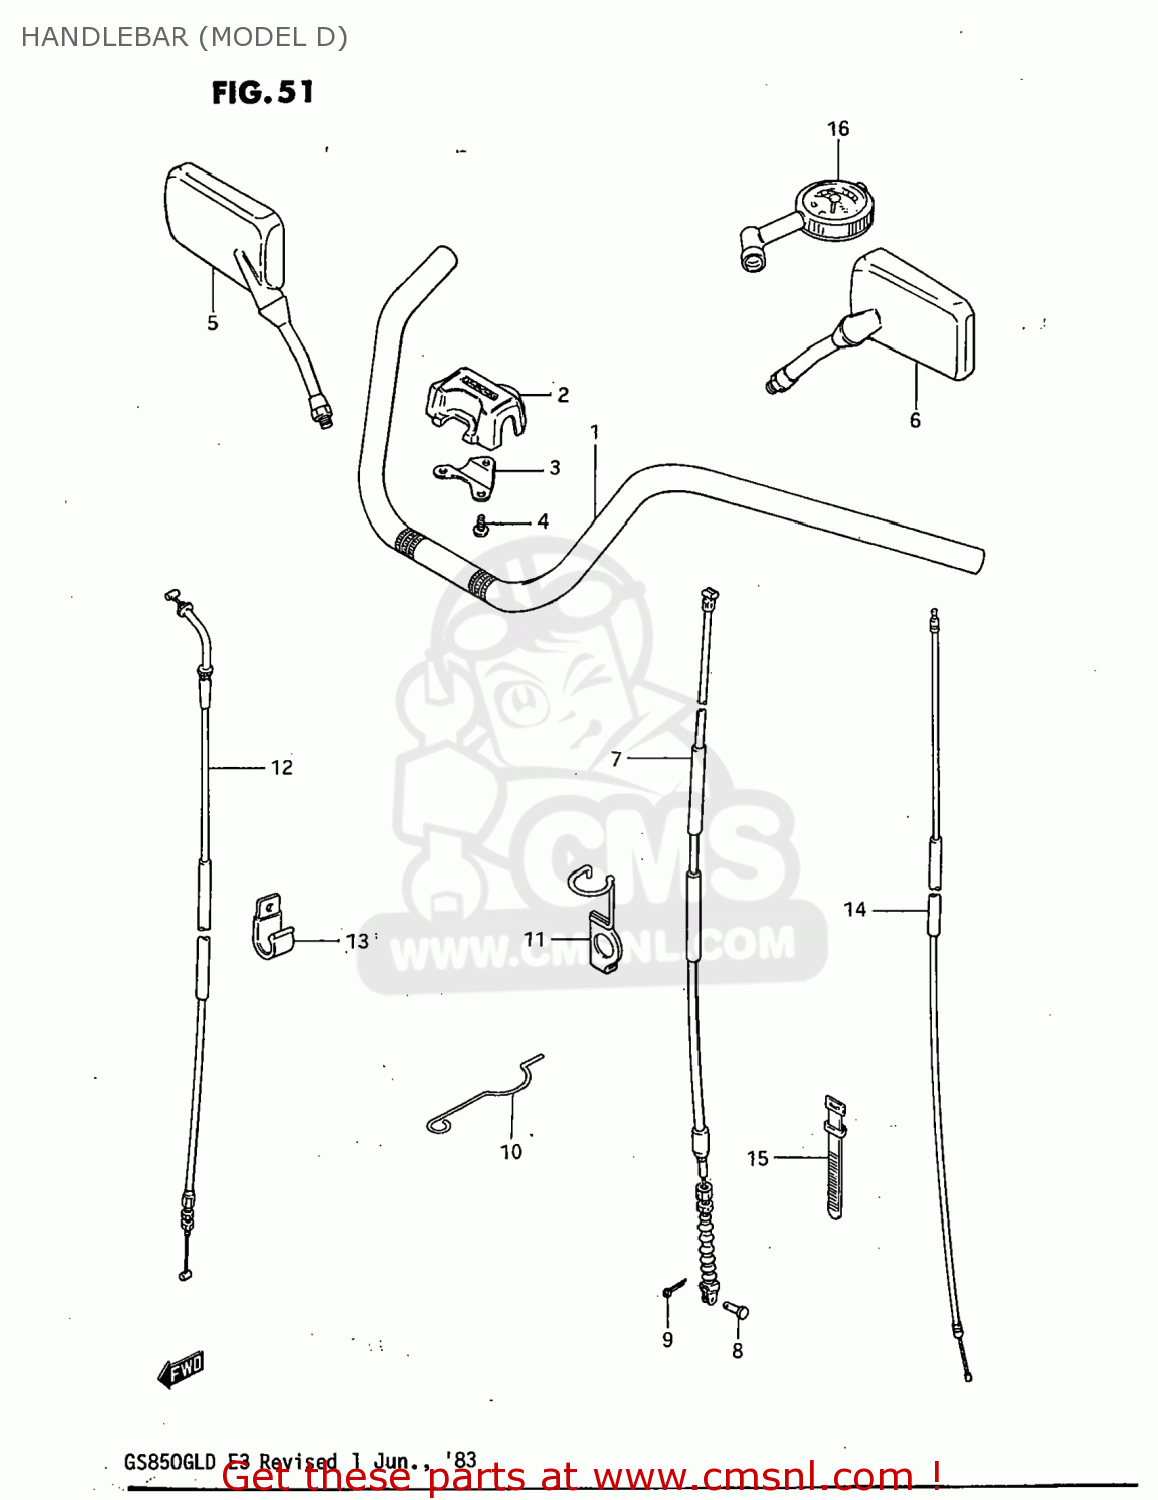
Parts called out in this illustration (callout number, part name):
1	HANDLEBAR
2	COVER,STEERING HEAD
3	BRACKET,STEERING HEAD
4	SCREW
5	MIRROR ASSEMBLY,REAR VIEW
6	MIRROR ASSEMBLY,REAR VIEW
7	CABLE ASSY,CLUTCH
8	PIN(L:15)
9	PIN
10	GUIDE,CABLE
11	GUIDE,CLUTCH CABLE
12	CABLE ASSEMBLY,THROTTLE
13	CLAMP
14	CABLE,STARTER
15	CLAMP(L:80)
16	GAUGE ASSY,AIR PRESSURE
